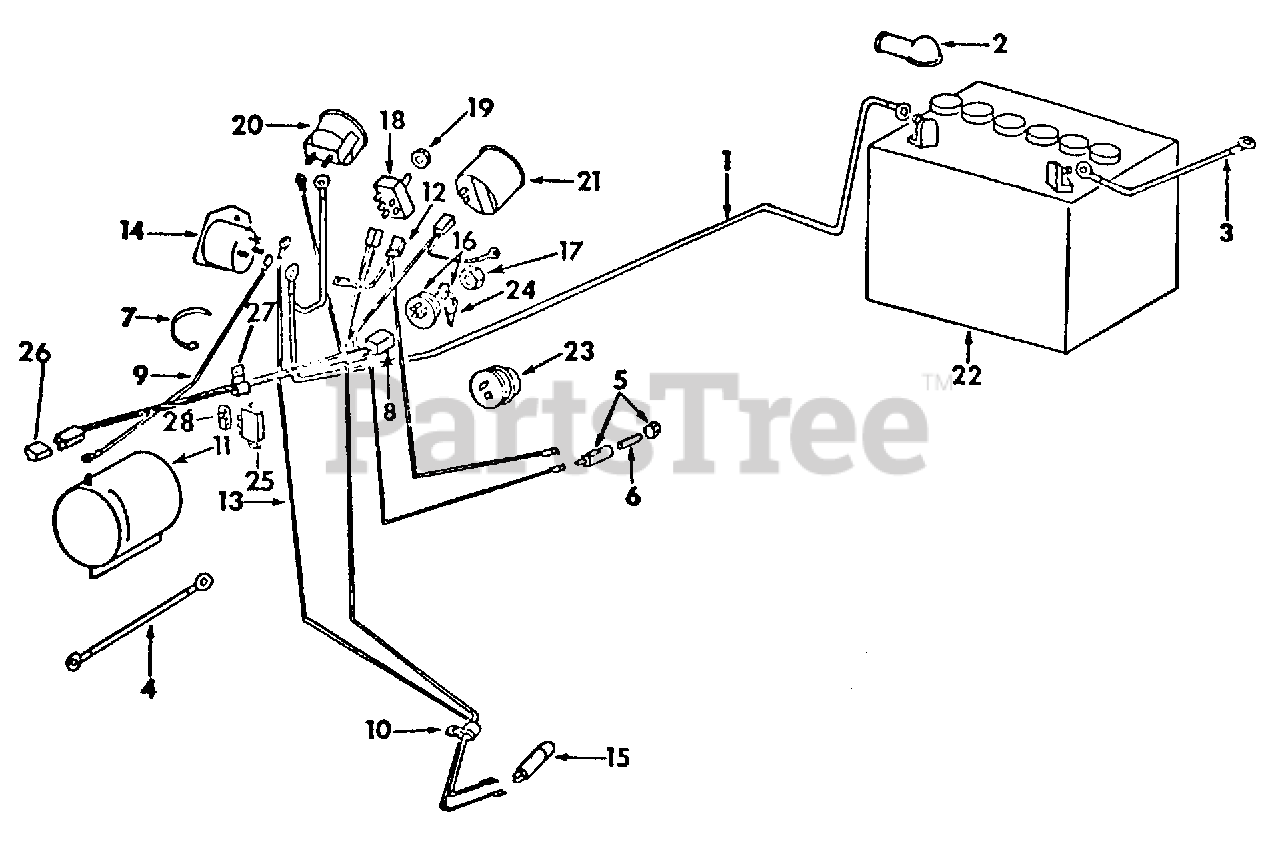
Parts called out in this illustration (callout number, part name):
1	Cable, Battery (Positive)
2	Cover, Battery Terminal
3	Cable, Battery Negative to Ground
4	Cable, Engine to Ground
5	Holder, Fuse
6	Fuse, 10 Amp
7	Strap, Cable Lock
8	Cable, Key Switch
9	Cable, Magnetic Switch to Cranking Motor
10	Clip, Cable (Steering)
11	Starter Motor Assy
12	Cable Assy, Clutch Switch
13	Cable, Magnetic Switch to Neutral Starting Switch
14	Switch, Magnetic
15	Switch, Neutral Start
16	Switch, Battery Ignition Key
17	Nut, Battery Ignition Switch
18	Switch, PTO
19	Nut, Switch
20	Indicator, Charge
21	Timer, Maintenance Minder
22	Battery, IH Low-Maintenance, 12 Volt
23	Not used in this application
24	Key, Battery Ignition Switch
25	Regulator Assy
27	Clip, Lead
28	Connector
